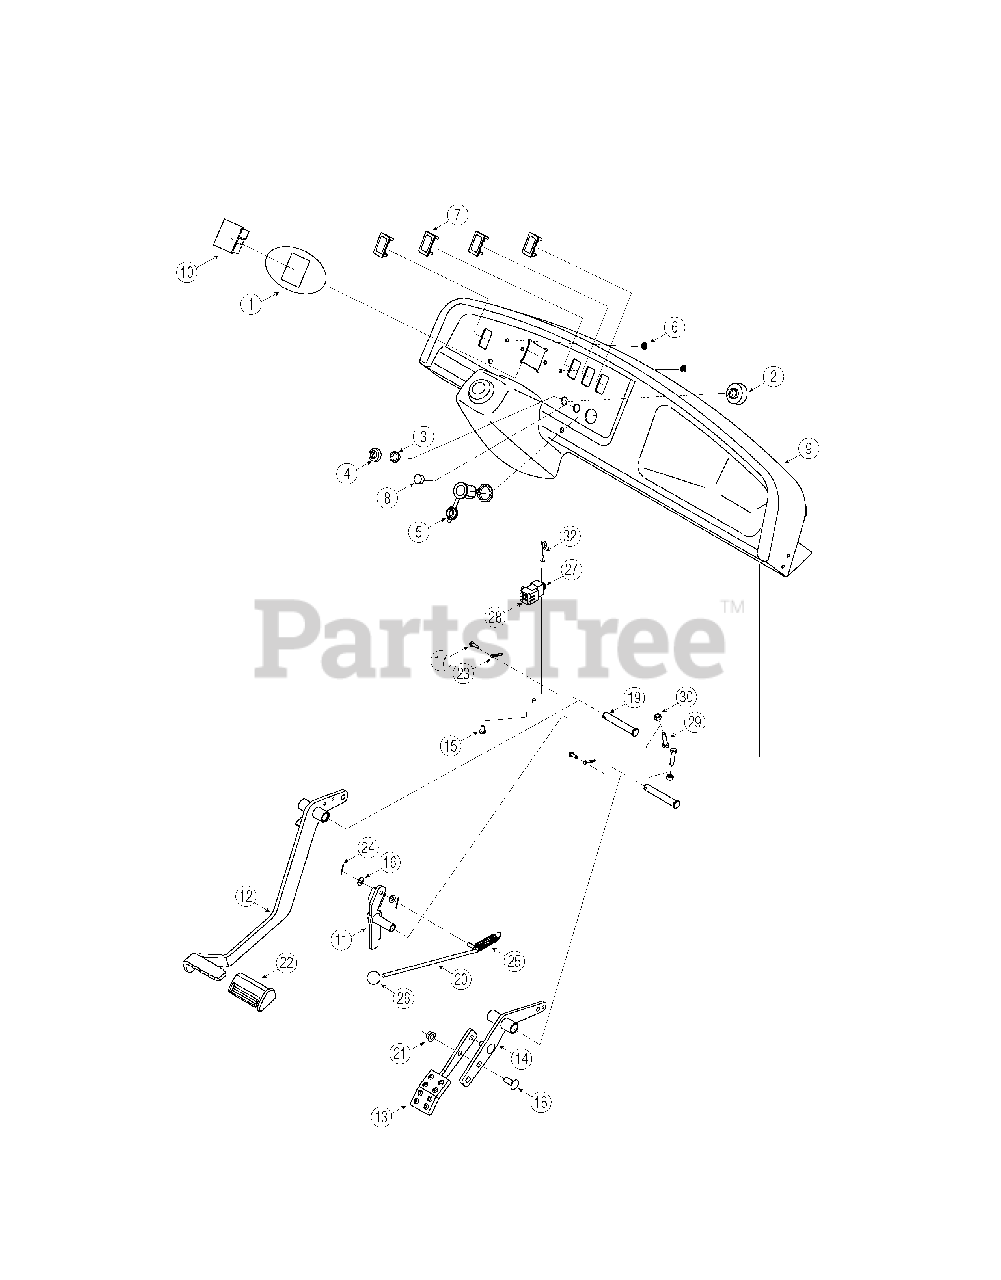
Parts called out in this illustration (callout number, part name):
1	Instrument Dash Cover
2	Key Switch
3	Nut, Ignition Switch, 5/8-32
4	Cap, Ignition Switch
5	Power Receptacle, 12V
6	Nut, Retainer, 1/8
7	Switch Plug Panel
8	Plug, Horn Switch
9	Dash Panel
10	Hour Indicator Meter
11	Lever, Parking Brake
14	Pedal Arm Assembly, Throttle
15	Screw, Hi-Lo, 1/4-20 x .5
16	Washer, Flat .25 x .630 x .0515
17	Screw, Self-tapping, #10-32 x.625
18	Bolt, Carriage, 3/8-16 x 1.0
19	Pin, Clevis.50 x 3.25
20	Rod, Brake Lock
21	Nut, Flange Lock, 3/8-16
22	Pad, Brake Pedal
23	Pin, Cotter, 5/32 x 1.00
24	Pin, Cotter, 1/16
25	Spring, Extension, .637 x 2.972
26	Knob, Ball
27	Cover, Protective
28	Snap Mount Switch, Interlock
29	Hex Screw, 5/16-18 x 1.25
30	Hex Nut, 5/16-18
32	Cotter Pin
